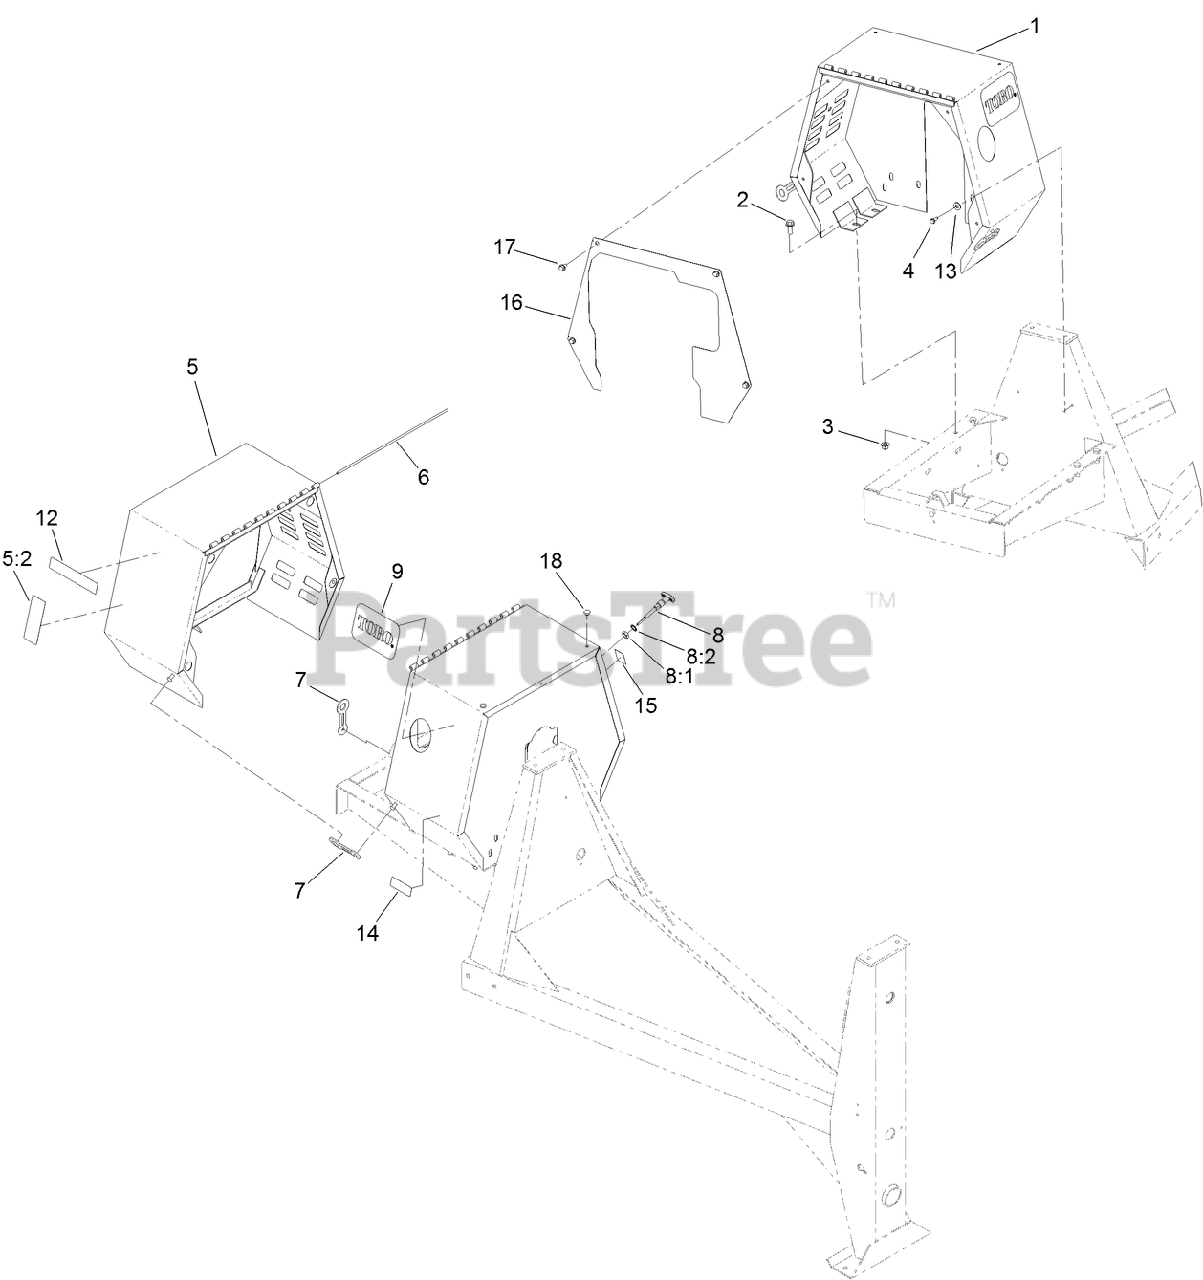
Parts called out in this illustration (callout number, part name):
1	COWL ASM
2	SCREW-HHF
3	NUT-LOCK
4	SCREW-THD ROLL, HWH
5	MOVABLE COWL ASM
5:2	DECAL-WARNING
7	LATCH-RUBBER
8	CABLE-THROTTLE, 125CM
8:1	NUT-JAM
8:2	WASHER-LOCK
9	DECAL
13	WASHER-FLAT
14	DECAL-ARRESTER, SPARK
15	DECAL-THROTTLE, DIESEL
16	PLATE-DRIVE, GUARD
17	SCREW-HWH
18	BUMPER
